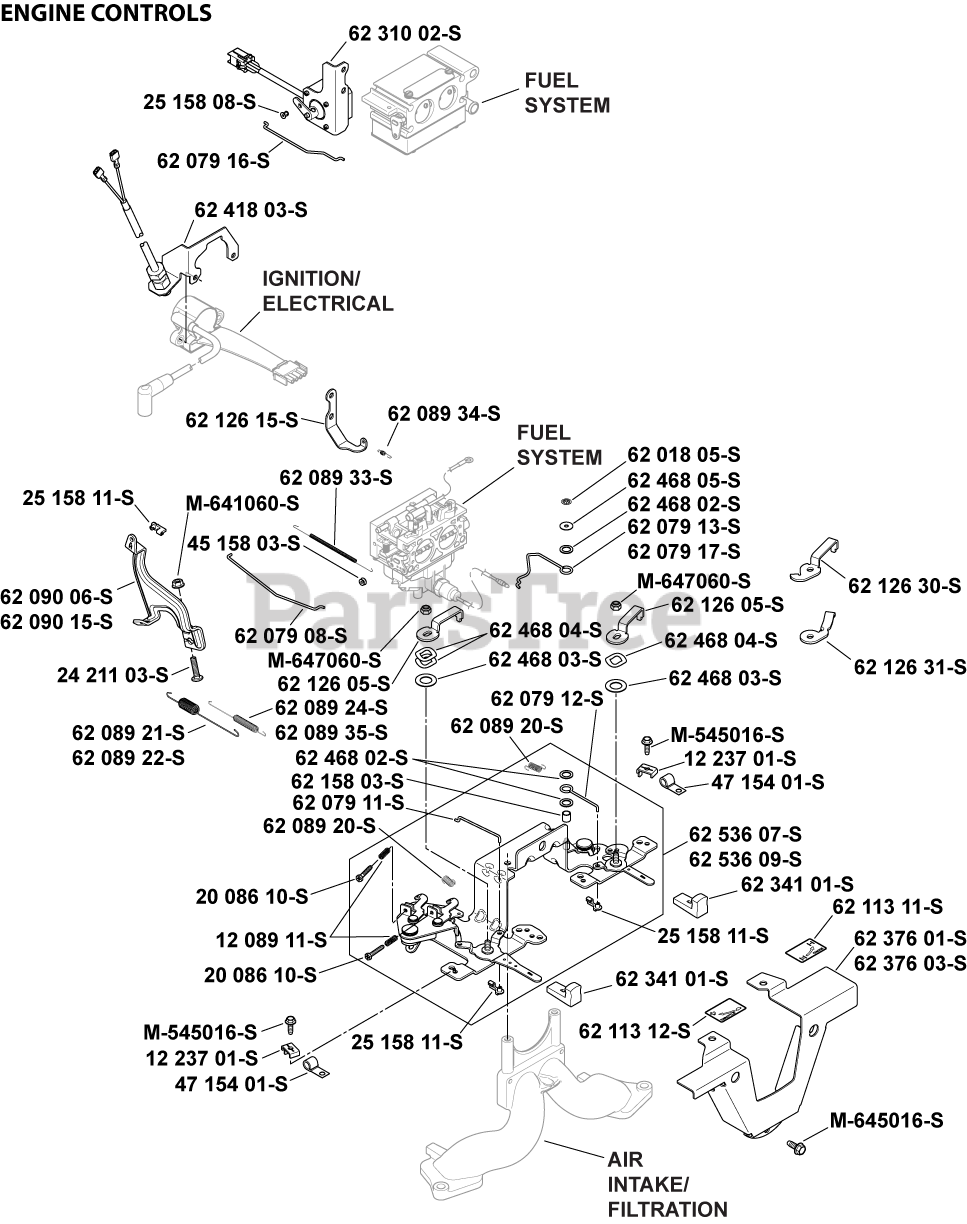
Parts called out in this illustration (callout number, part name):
1	BUSHING, THROTTLE LINKAGE
2	KIT, GOVER LEVER-CH940-980
3	BOLT, RD HD SQ NECK M6X1.0X25
4	SPRING, GOVERNOR
5	SPRING, GOVERNOR
7	CLAMP, CABLE
8	SCREW, THREAD FORMING
9	SCREW, PHL THD FRM M4X0.7X25
11	SPRING, RETURN
12	LINKAGE, THROTTLE LEVER
14	WASHER, NYLON
16	NUT, LOCK M6X1.0
17	LINKAGE, THROTTLE
19	NUT, FLG M6X1.0
20	BRACKET, CHOKE ASSIST
23	BUSHING, LINKAGE RETAINING
25	SPRING, CHOKE ASSIST
26	SPRING, LINKAGE
27	WASHER, SPRING
29	LINKAGE, CONTROL
30	KNOB, CONTROL LEVER
35	CONTROL ASSEMBLY, SPEED (HORIZONTAL)
36	BRACKET, MANUAL CHOKE CONTROL
38	RETAINER, PALNUT
39	WASHER, STEEL
40	LINKAGE, CHOKE HORIZONTAL
41	WASHER, NYLON SHOULDER
62	WASHER, FLAT 9 MM
